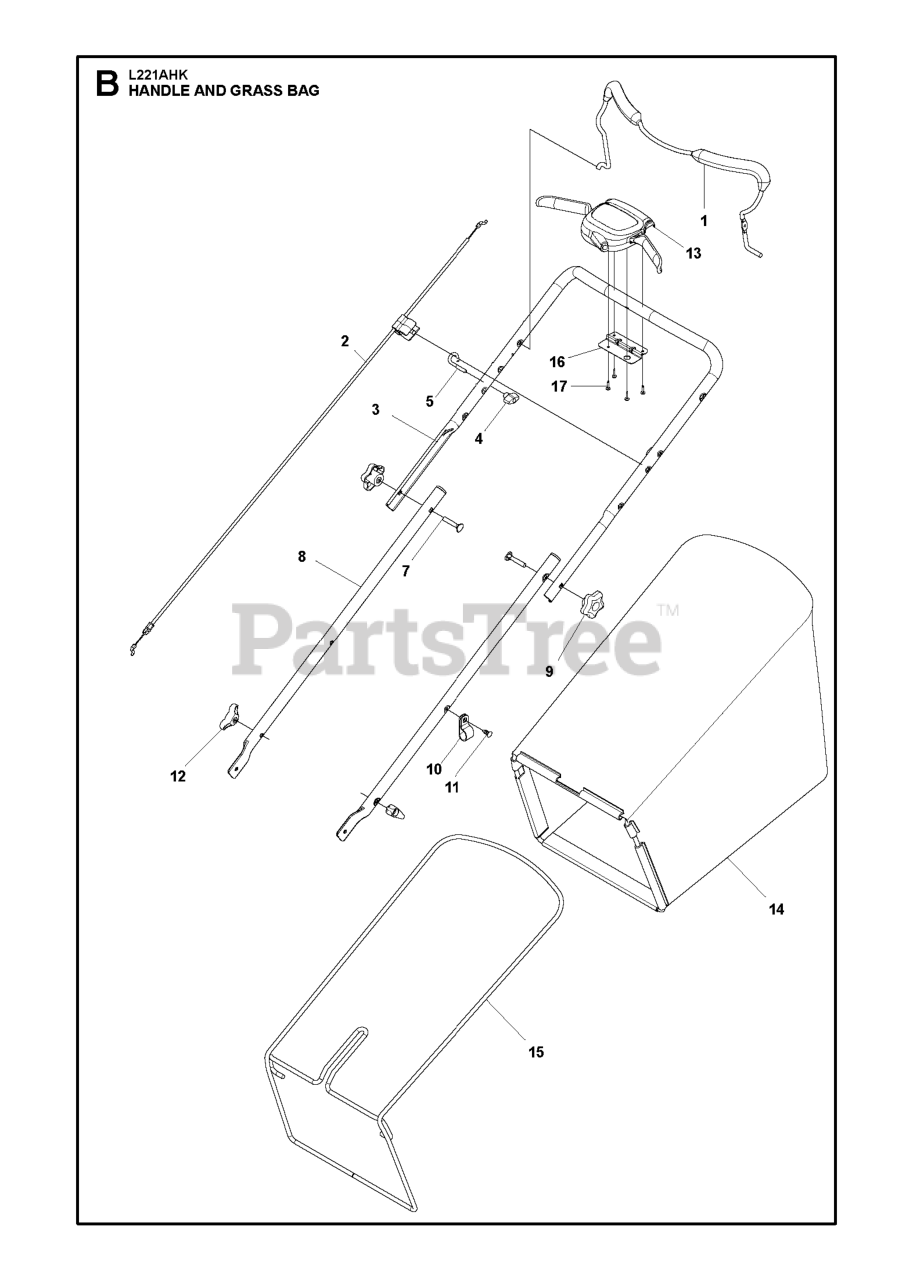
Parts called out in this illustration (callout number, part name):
1	BAIL.OM.ERGO.BENT.MZR.ORAN.668
2	CABLE.MZR.ZONE.CONTROL
3	HANDLE.UPPER.3.POS.BS.AW2.GREY
4	T-KNOB.NEW ROPE GUIDE
5	GUIDE.ROPE.BLK.ZINC.CHROM
7	BOLT.CONCAVE.HEAD.RETAINING
8	HANDLEBAR ASSY TWO PIECE LOWER
9	KNOB.HANDLE.PLASTIC.STAR.BLACK
10	CLIP.CABLE.BLK
11	FASTENER.PUSH.O.250X0.783
12	KNOB, DEFLECTOR
13	CONTROL.AW2.GEN.CURVED.AW/RGD.
14	GBAG.C361029EM.HUSQ.GRY.21EFF
15	FRAME.GBAG.AWD.21.BLACK
16	BRACKET DUAL TRIGGER CONTROL
17	SCREW, PHILLIPS HEAD 10 X 5/8
